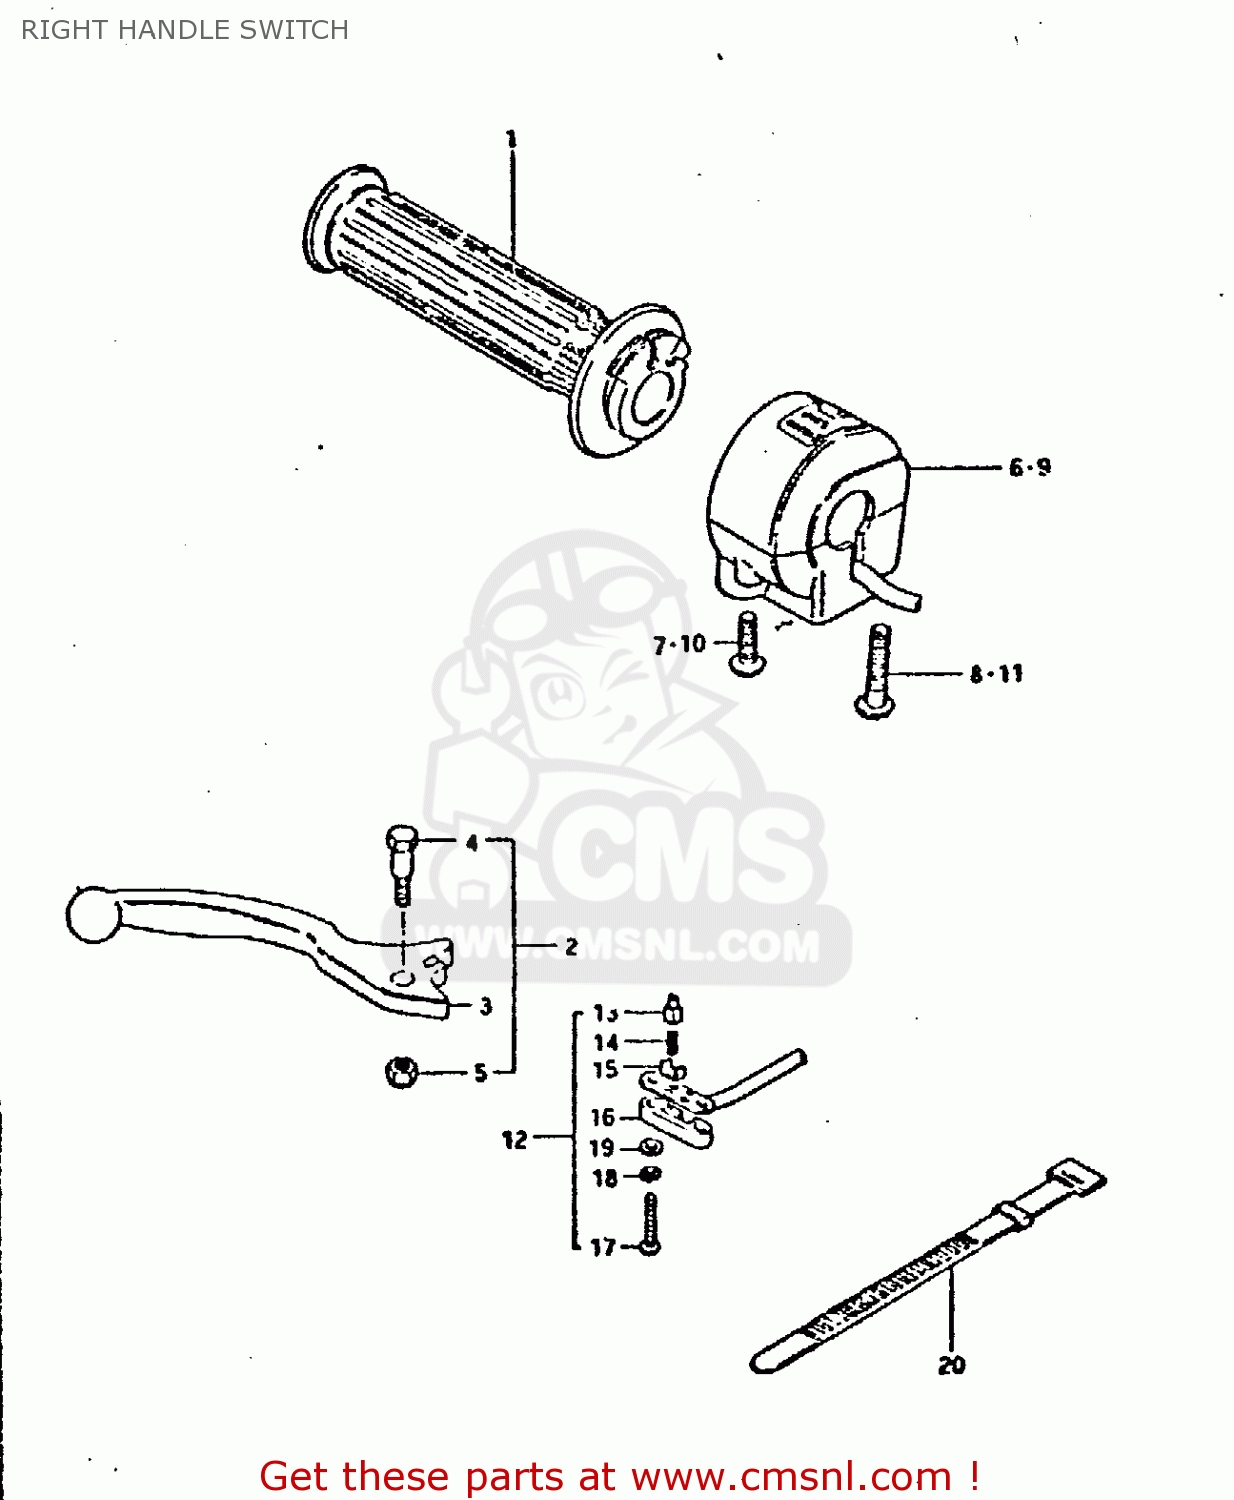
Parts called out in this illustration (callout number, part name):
1	GRIP,THROTTLE
2	LEVER ASSEMBLY,BRAKE
3	LEVER,BRAKE
4	BOLT
5	NUT 6MM
6	SWITCH ASSEMBLY,HANDLE,RIGHT
7	SCREW
8	SCREW
20	CLAMP(L:120)
